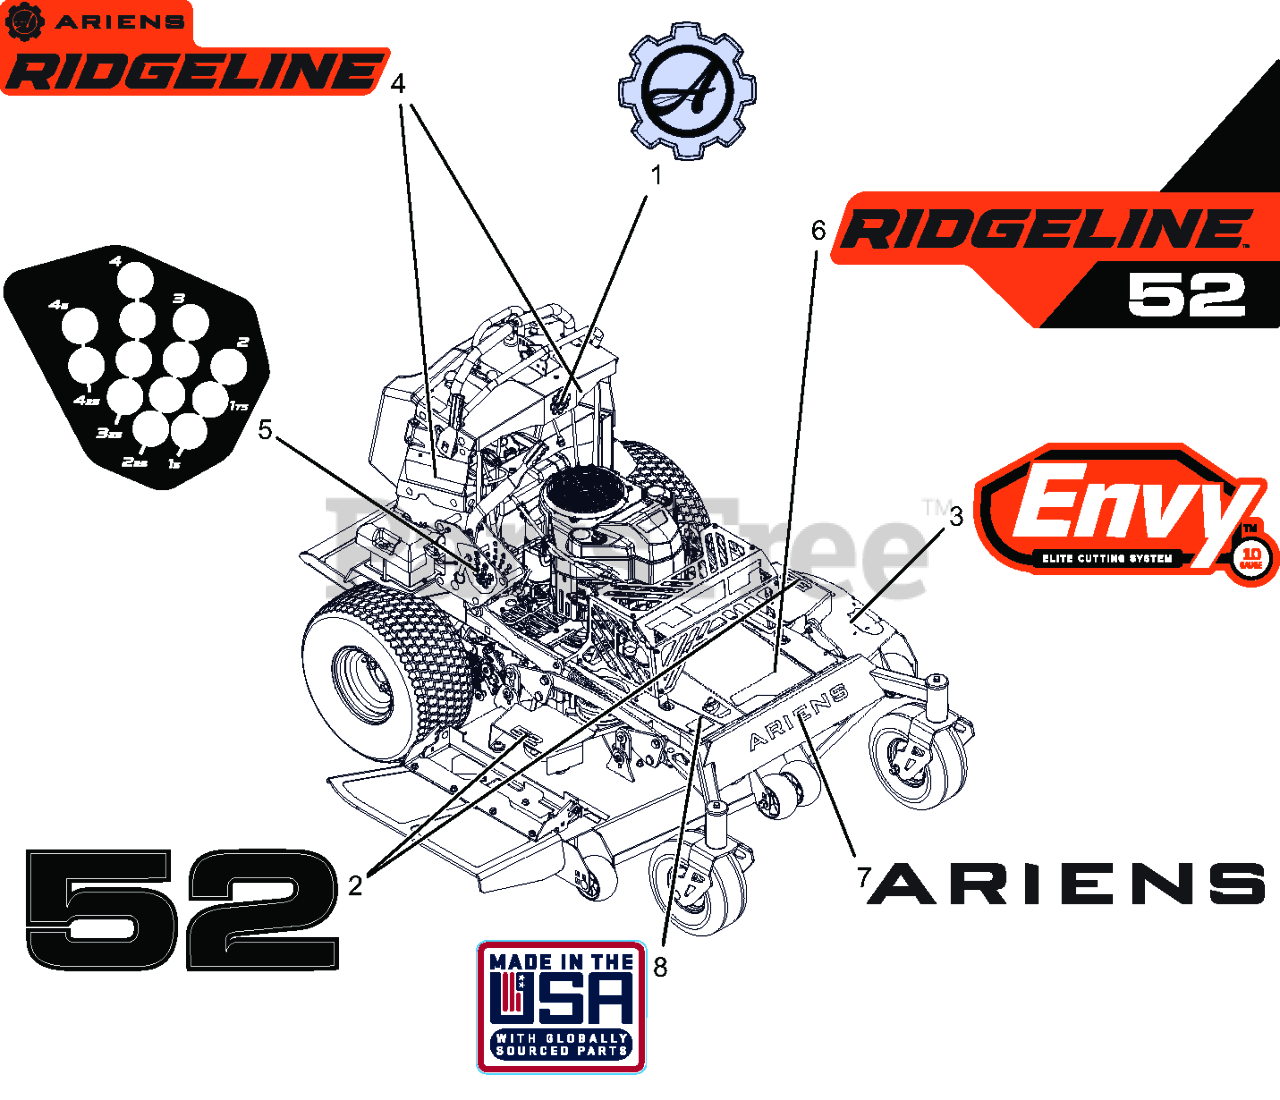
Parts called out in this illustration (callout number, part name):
1	DECAL- ARIENS GEAR BADGE
2	DECAL- DECK 52
3	DECAL- DECK -ENVY
4	DECAL- TOWER
5	DECAL- HOC
6	DECAL- RIDGELINE 52"
7	DECAL- ARIENS 15.0" BLACK
8	DECAL, MADE IN USA
